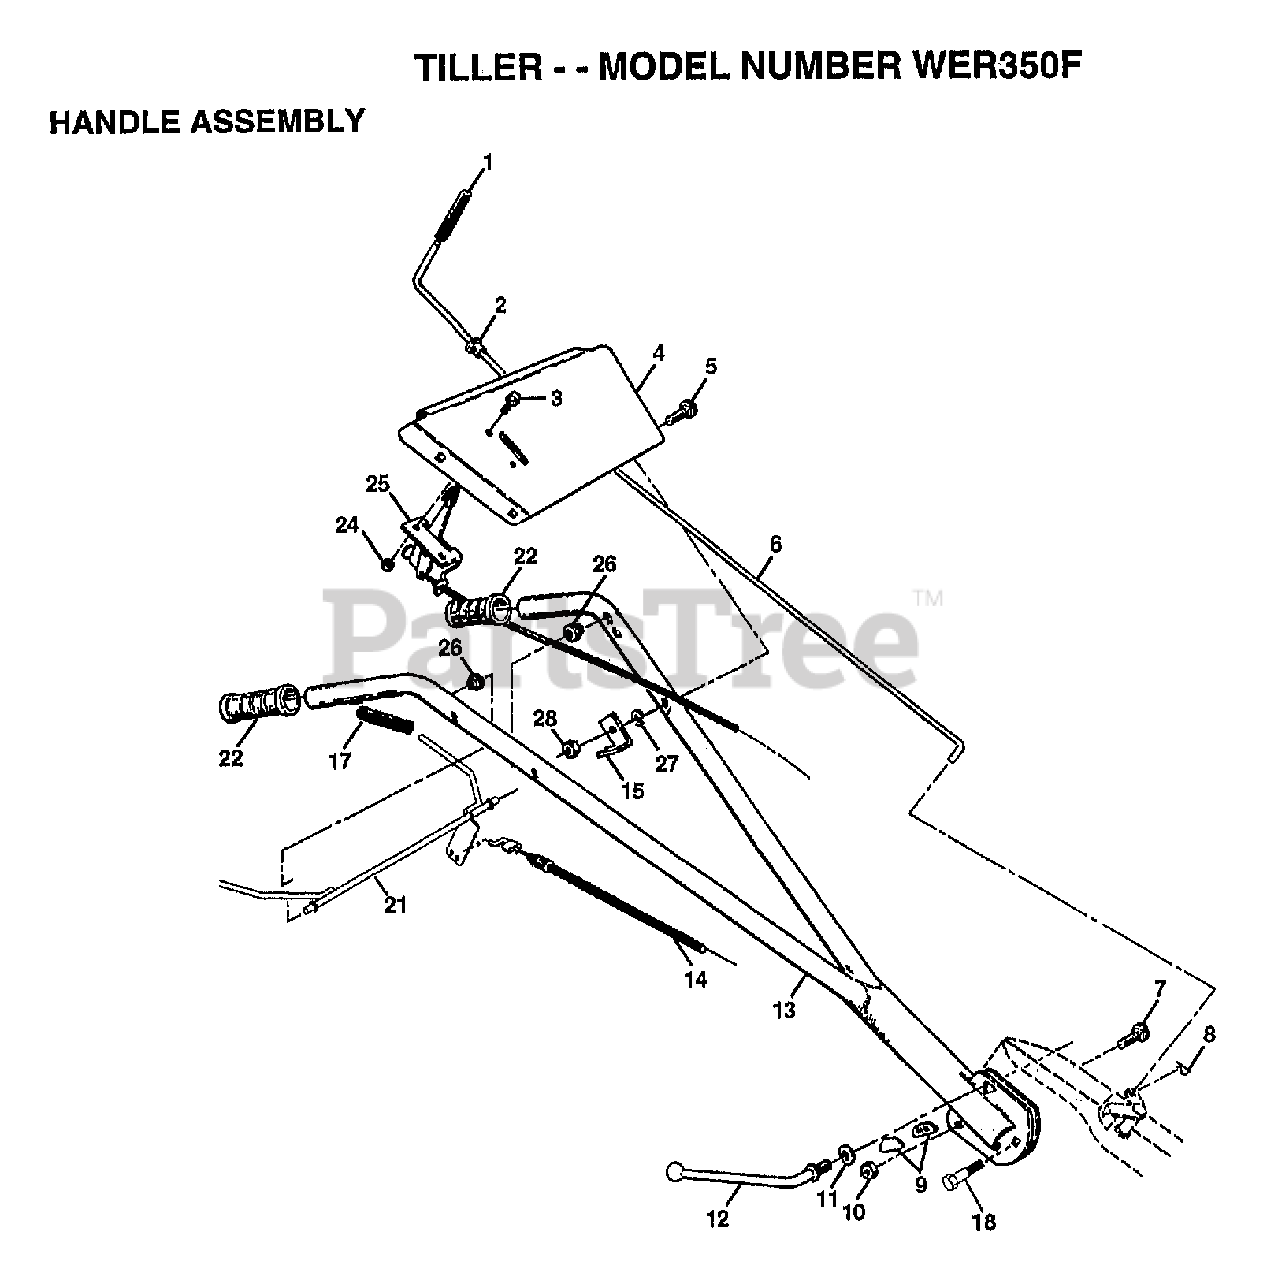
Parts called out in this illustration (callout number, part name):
1	GRIP TI
2	BUSHING
3	SCREW.PNHD.10-24
4	HANDLE BRACKET
5	BOLT CARRIAGE CRT
6	ROD SHIFT CRT
7	BOLT D
8	RETAINER M
9	LOCK CRT
10	LOCKNUT
11	WASHER CRT
12	LEVER LOCK CRT
14	"CABLE, CLUTCH"
15	BRACKET.CLUTCH.CA
17	GRIP BAR CRT
18	BOLT PIVOT
21	BAR CONTROL
22	"GRIP,HANDLE"
25	"CONT,THROTTLE"
26	GROMMET.HANDLE.V-
27	LOCKWASHER
28	NUT
